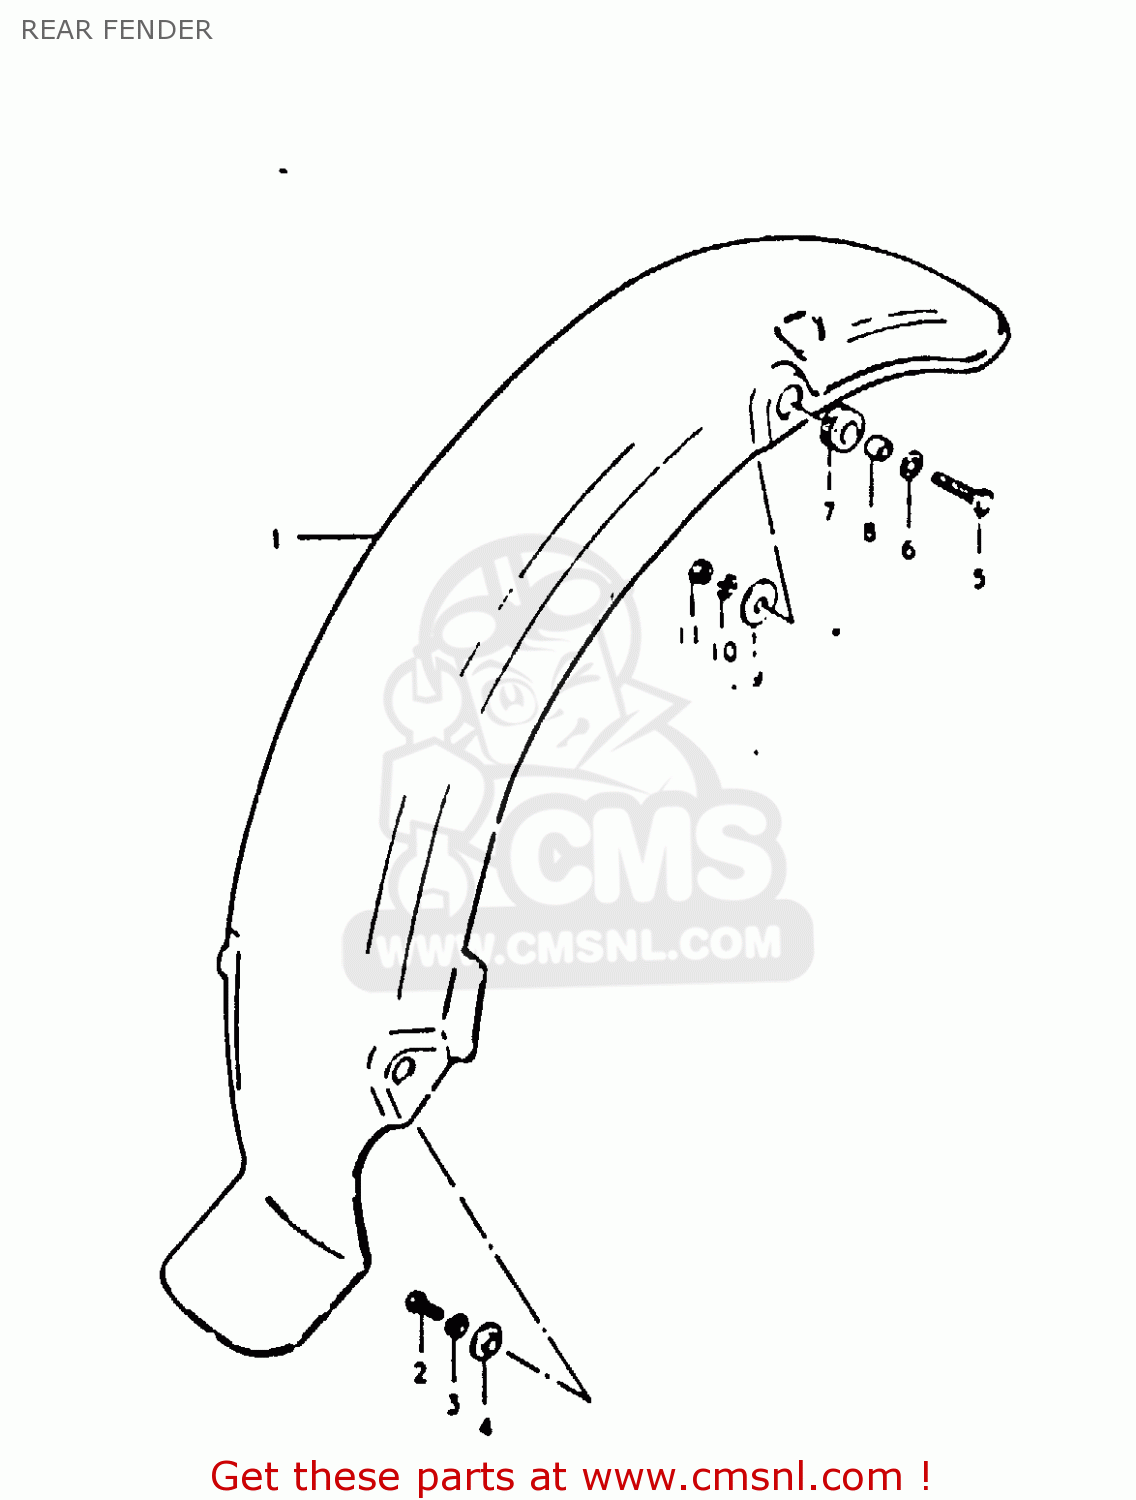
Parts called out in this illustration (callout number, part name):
1	FENDER,REAR
2	BOLT, UPPER
3	LOCK WASHER
4	WASHER
5	BOLT
6	WASHER
7	CUSHION
8	SPACER (8.2X12X7.5)
9	WASHER(8.5X26X1.2)
10	LOCK WASHER
11	NUT
